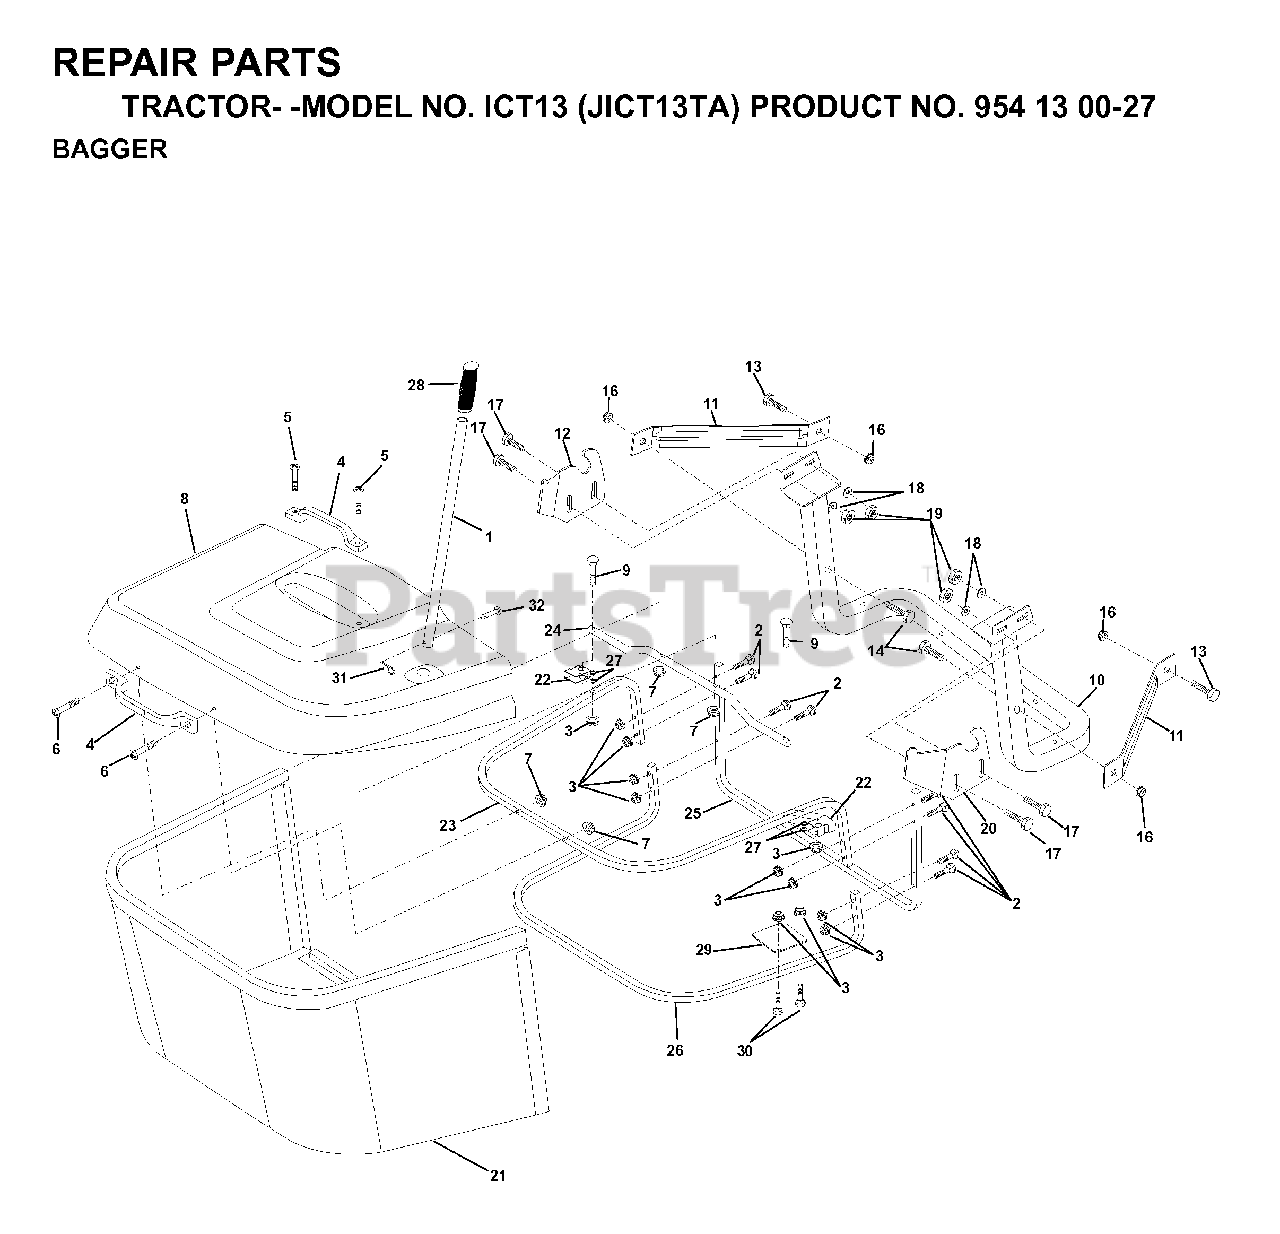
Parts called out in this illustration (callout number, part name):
1	TUBE HANDLE
3	NUT T
5	SCREW.PAN.HEAD
8	COVER
11	BRACKET
16	NUT LOCK FLG 3/8-16 UNC
17	BOLT
19	NUT.71038.31-18.HEX.NYLOCK
21	BAG
22	BRACKET
23	TUBE
24	TUBE
26	TUBE
28	GRIP.HANDLE.BLACK
31	RETAINER M
32	RIVET,DRILLED
